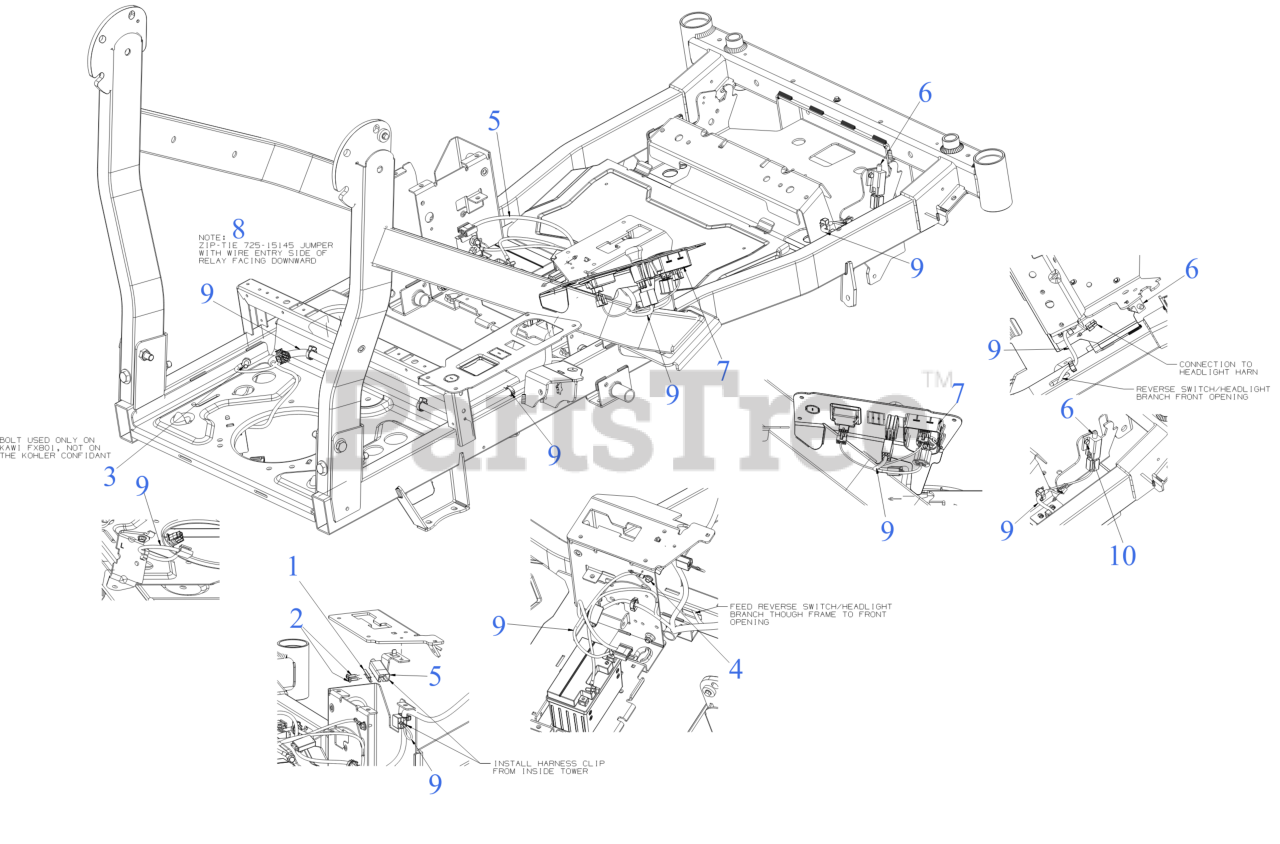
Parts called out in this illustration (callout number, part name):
1	PLATE-SWITCH
2	SCREW #10-24X11/16 T-25
3	SCREW M8-1.25 x 16 Gr8.8
4	SCREW 1/4-20X.625
5	SCREW MOUNT SWITCH NO/NC
6	INTERLOCK SWITCH (NO/NC)
7	IGNITION MODULE SWITCH (RMC ELC PTO WHTE)
8	JUMPER HARNESS (W/RELAY)
9	MAIN HARNESS (KH-ZT/KAW)
9	12V SOLENOID
10	SHOULDER SCREW
